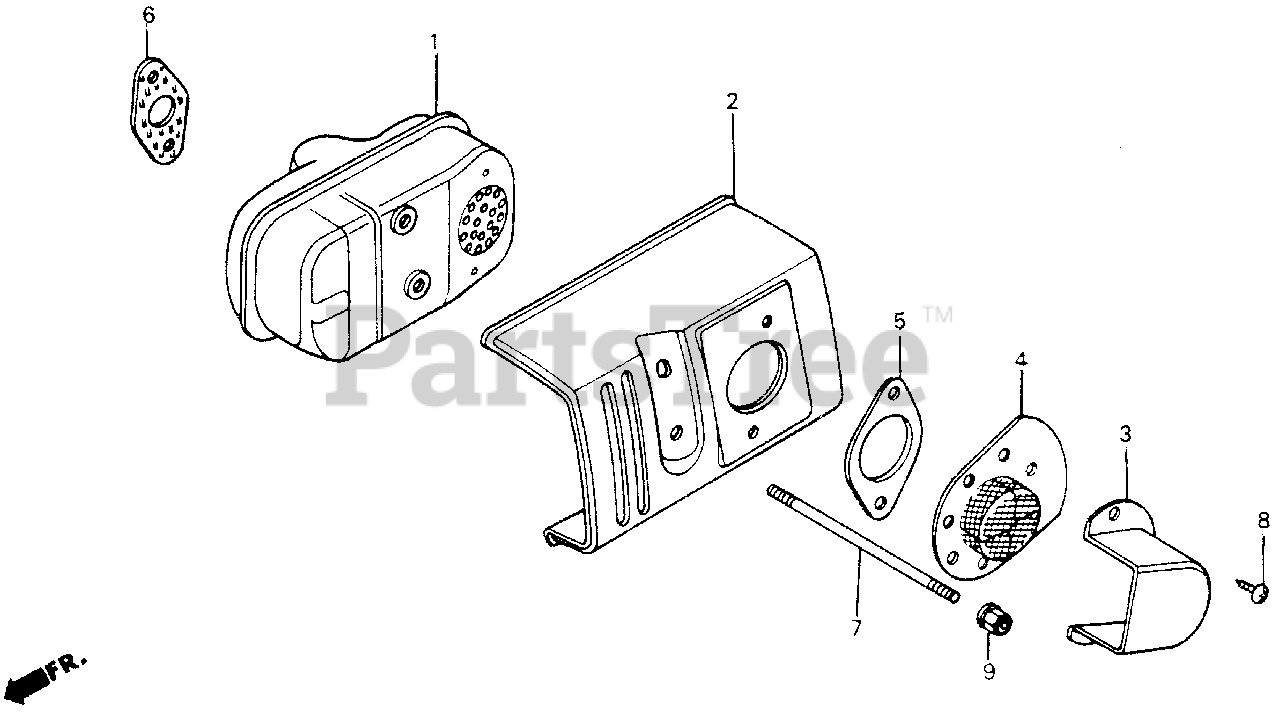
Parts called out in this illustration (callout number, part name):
1	MUFFLER (NOT AVAILABLE)
2	PROTECTOR, MUFFLER
3	CAP, MUFFLER
4	ARRESTER, SPARK (NOT AVAILABLE)
5	GASKET, MUFFLER ARRESTER (NOT AVAILABLE)
6	GASKET, MUFFLER
7	BOLT, STUD (6X93)
7	BOLT, STUD (6X82)
8	SCREW, TAPPING (4X8)
9	NUT, SELF-LOCK (6MM)
